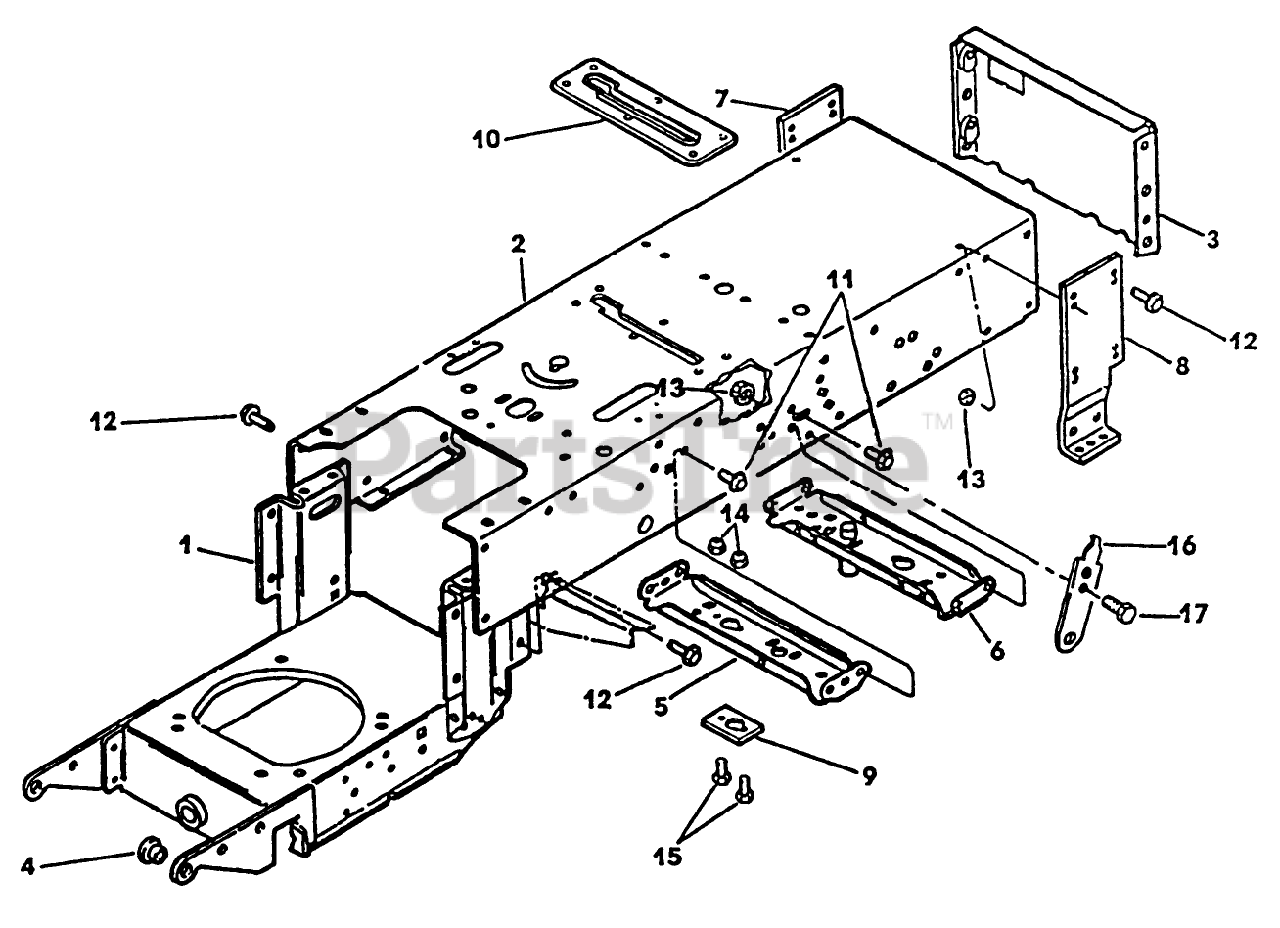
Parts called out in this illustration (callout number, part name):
2	FRAME & STICKER AY(12)
4	BEARING-NYLINER
5	SUPPORT *B
9	BRACKET-SUPPORT *B
13	NUT
14	NUT-LOCK, CONE
15	SCREW
16	ARM-MOWER LIFT
17	SCREW
